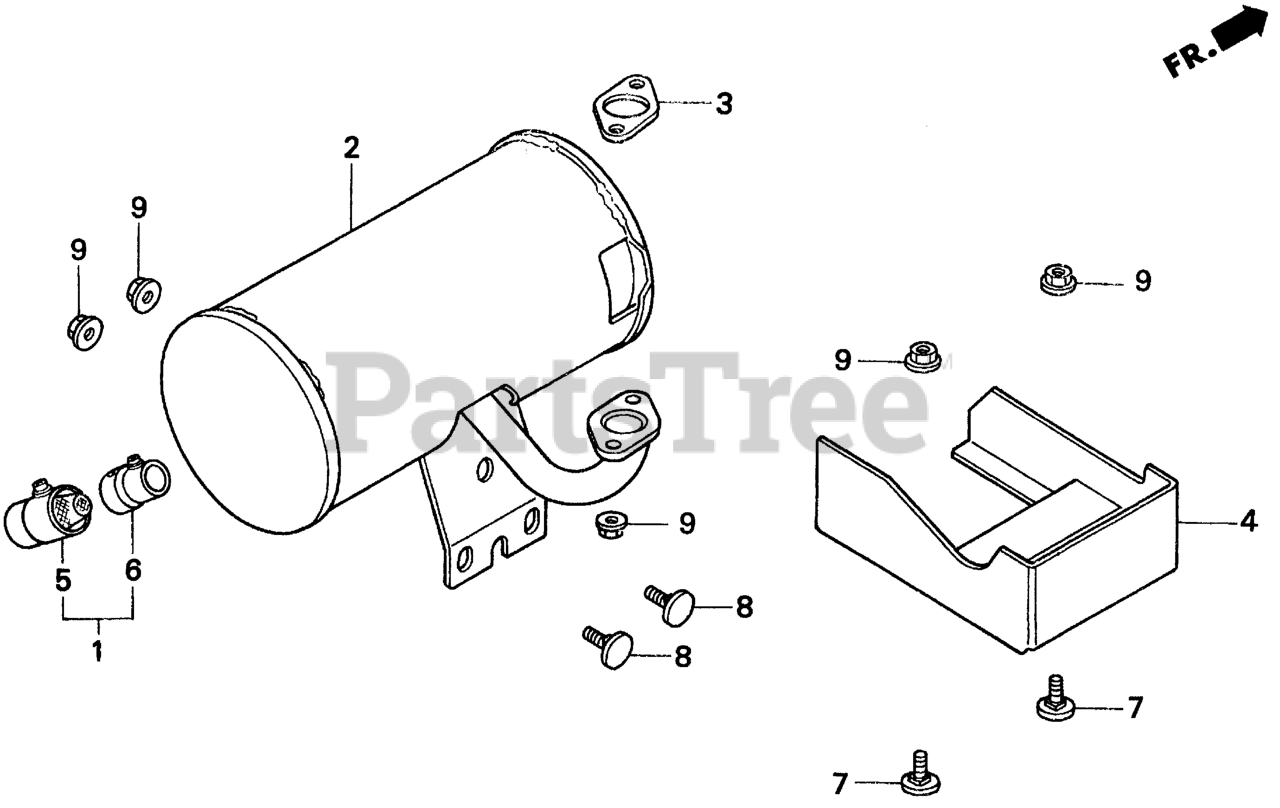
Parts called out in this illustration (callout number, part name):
1	ARRESTER KIT, SPARK
2	MUFFLER, EX.
3	GASKET, EX. PIPE Use up to Engine SN 2949254.
3	GASKET, EX. PIPE (WACKER)
4	PROTECTOR, HEAT (LOWER)
5	ARRESTER, SPARK
6	ADAPTER, SPARK ARRESTER
7	BOLT, SPECIAL (8X20)
8	BOLT, SPECIAL (9X15)
9	NUT, FLANGE (8MM)
